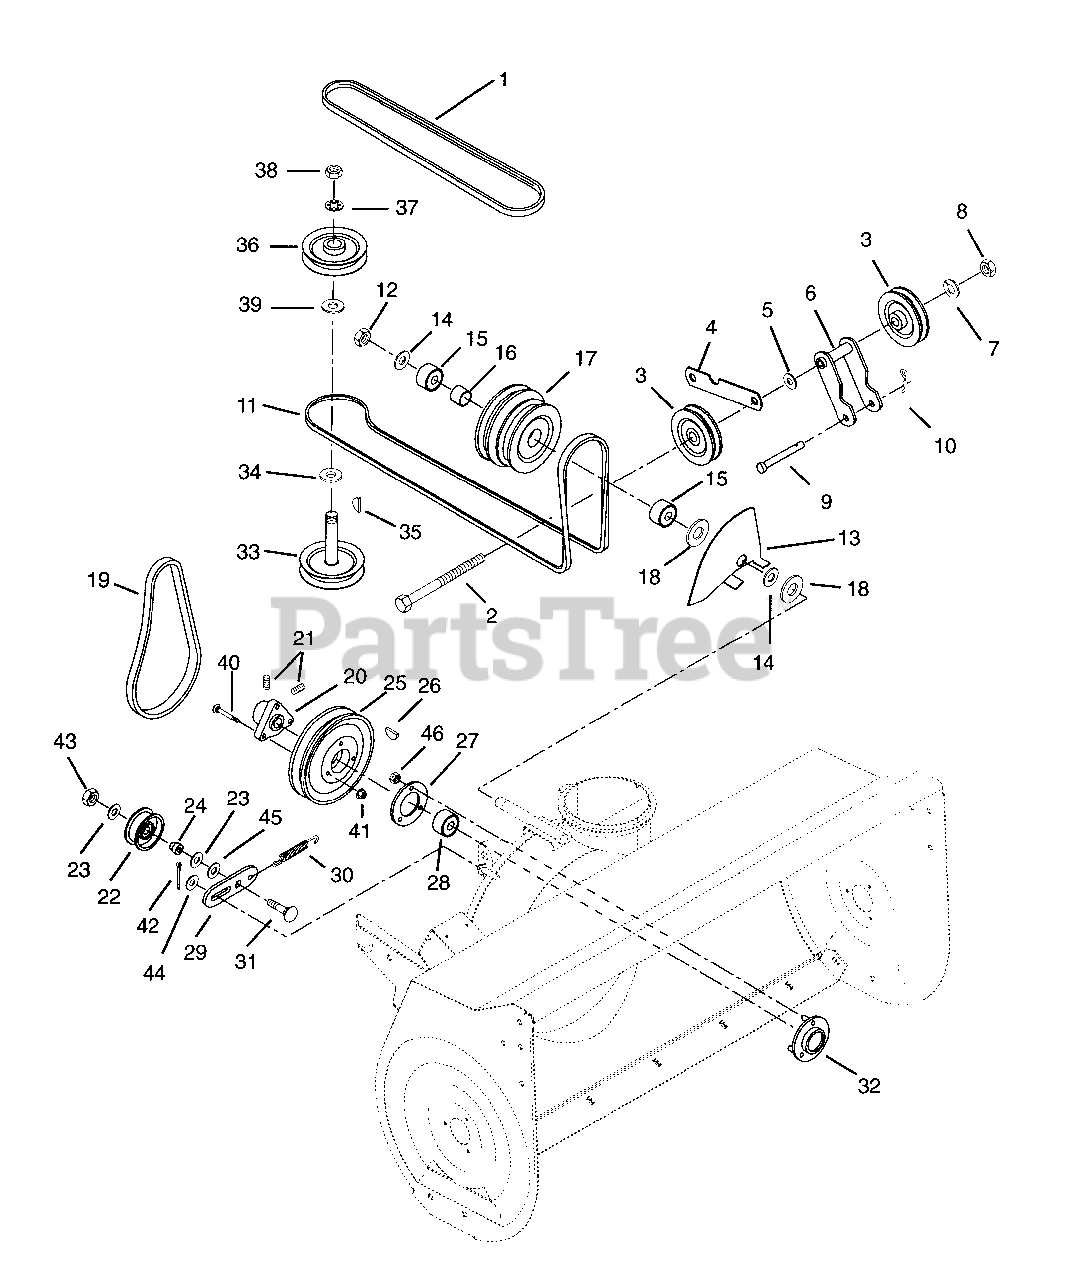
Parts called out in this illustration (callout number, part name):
1	V-BELT, HA-RAW EDGE
2	@BLT-HEX .38-16X5.00 GR5 YWZC
3	IDLER-V 4.00 X .38 NWHAMSHR
4	STRAP
5	WSHR-FL-STL .754X1.000X.032 YZ
6	IDLER BRACKET
7	@WSHR-LK .38X.094 REG YWZC
8	@NUT-HEX .38-16 YWZC
9	CLEVIS PIN 3/8X3.0 YWZC
10	PIN-HAIR INT .08X.38X1.42 YWZC
11	V-BELT, HA-WRAPPED
12	NUT-LK-CTR .75-10 PL
13	SHIELD
14	WSHR-FL-STL .781X1.250X.059 PL
15	BRG-BALL .750X1.781X.61
16	SPACER 1.00 X .770/.760 X .813
17	SHEAVE, DOUBLE
18	WSHR-FL-STL .781X1.500X.188
19	V-BELT, 4L-RAW EDGE
20	HUB
21	SCR-SET .31-18X.38 SKHCUPDL
22	IDLER
23	WSHR-FL-STL .390X.88X.18 YWZC
24	SPACER -FLANGED .390X.500X.781
25	PLY-V 9.0 X 1.25 3BLT
26	KEY-WDRF .188X.875X.375 SAE11
27	BEARING FLANGE
28	BRG-BALL1.0X2.0X.56
29	IDLER ARM
30	SG-TENS .090X.75X3.50 WLD 34
31	@BLT-RDHDSQNK .38-16X1.75 G5YZ
32	BEARING FLANGE
33	SPINDLE SHAFT
34	SPACER .755X1.250X.370
35	KEY-WDRF .188X.75X.313 SAE 9
36	PLY-V 4.50 X .75 W/KEY SALEM
37	WSHR-LK-INT .750 YWZC
38	NUT-JAM .75-10 YWZC
39	@WSHR-LK .75X.188 REG YWZC
40	BLT-SERRDHD SL .31-18X.87 PL
41	@NUT-SPNLK-FLG .312-18 YWZC
42	@PIN-CTR .12X.75 EXTPRSQCT YWZ
43	@NUT-LK-CTR .38-16 YWZC
44	WSHR-FL-STL .382X.812X.023YWZC
45	@WSHR-FL-STL.438X1.00X.083 YWZ
46	@WSHR-FL-STL.38X.875X.083 YWZC
